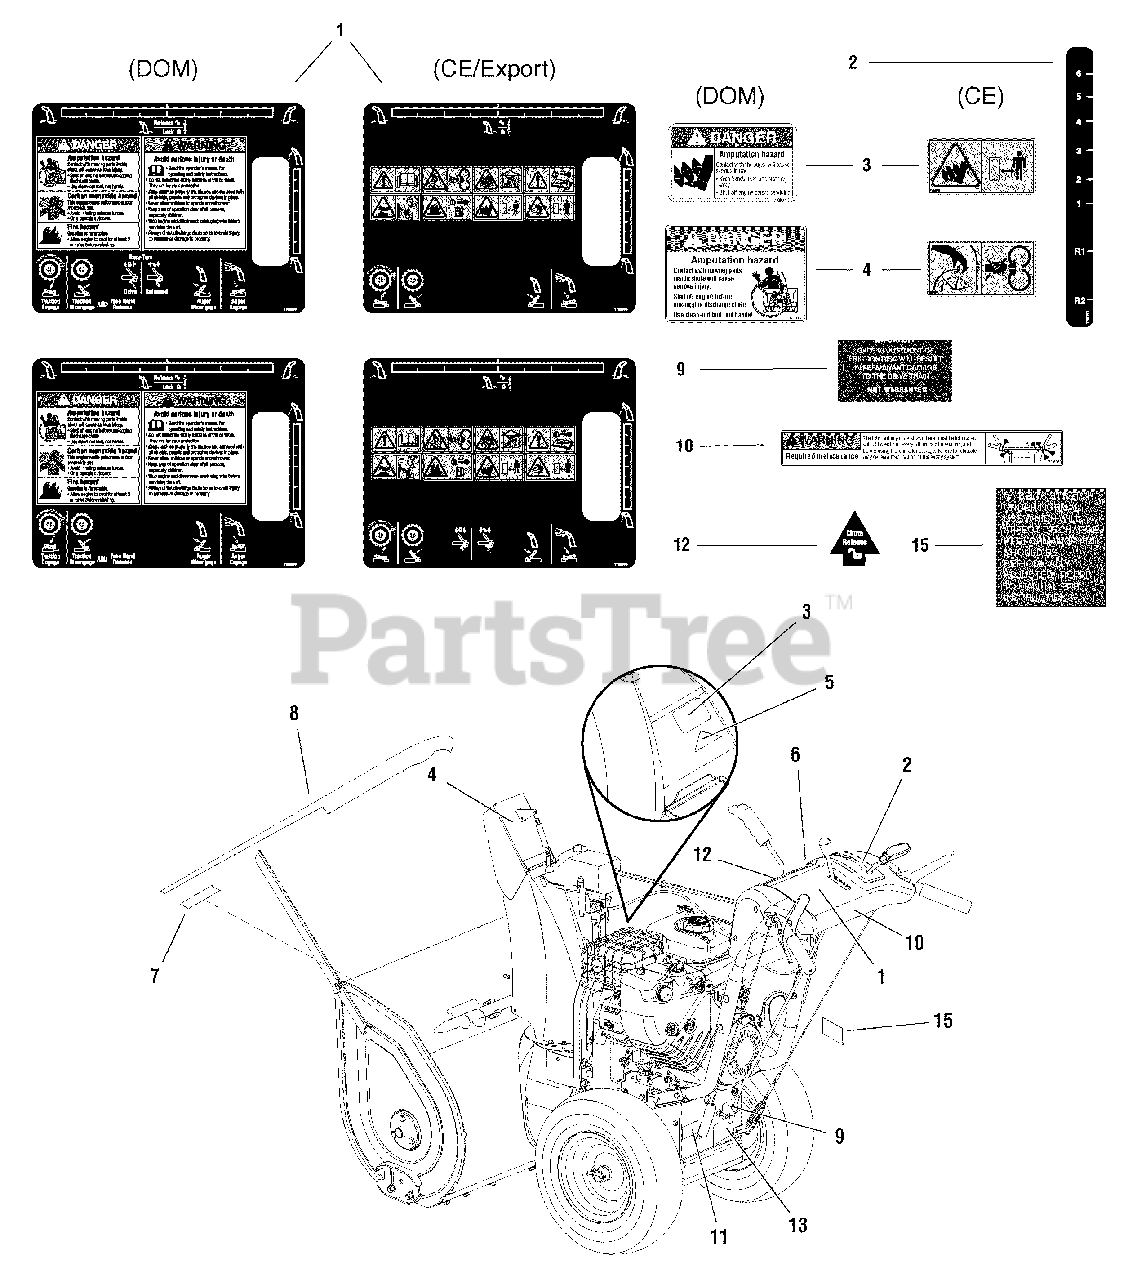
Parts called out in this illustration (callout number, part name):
1	DECAL, Dashboard Standard Drive
1	DECAL, Dashboard EZ Turn
2	DECAL, Shift 1,2,3,4,5,6 R1 R2
3	DECAL, Danger Avoid Injury From Auger
3	DECAL, Impeller Warning
4	DECAL, Danger Amputation Hazard
4	DECAL, Chute Warning
5	DECAL, Opei Certified ANSI
6	DECAL, SMI Dash Swoosh
7	DECAL, SMI 1428L
7	DECAL, SMI 1226L
7	DECAL, SMI 1530L
7	DECAL, SMI 1632L
8	DECAL, SMI Stripe 27.07 Long
8	DECAL, SMI Stripe 25.09 Long
8	DECAL, SMI Stripe 29.00 Long
8	DECAL, SMI Stripe 31.00 Long
9	DECAL, Over Adjustment of Friction Disc
10	DECAL, Warning Lubrication
11	DECAL, Touch Up Paint Orange, Black, Red
12	DECAL, Chute Release Arrow
13	STICKER, Serial w/Bar Code
15	DECAL, Belt Stretch & Adjustment
